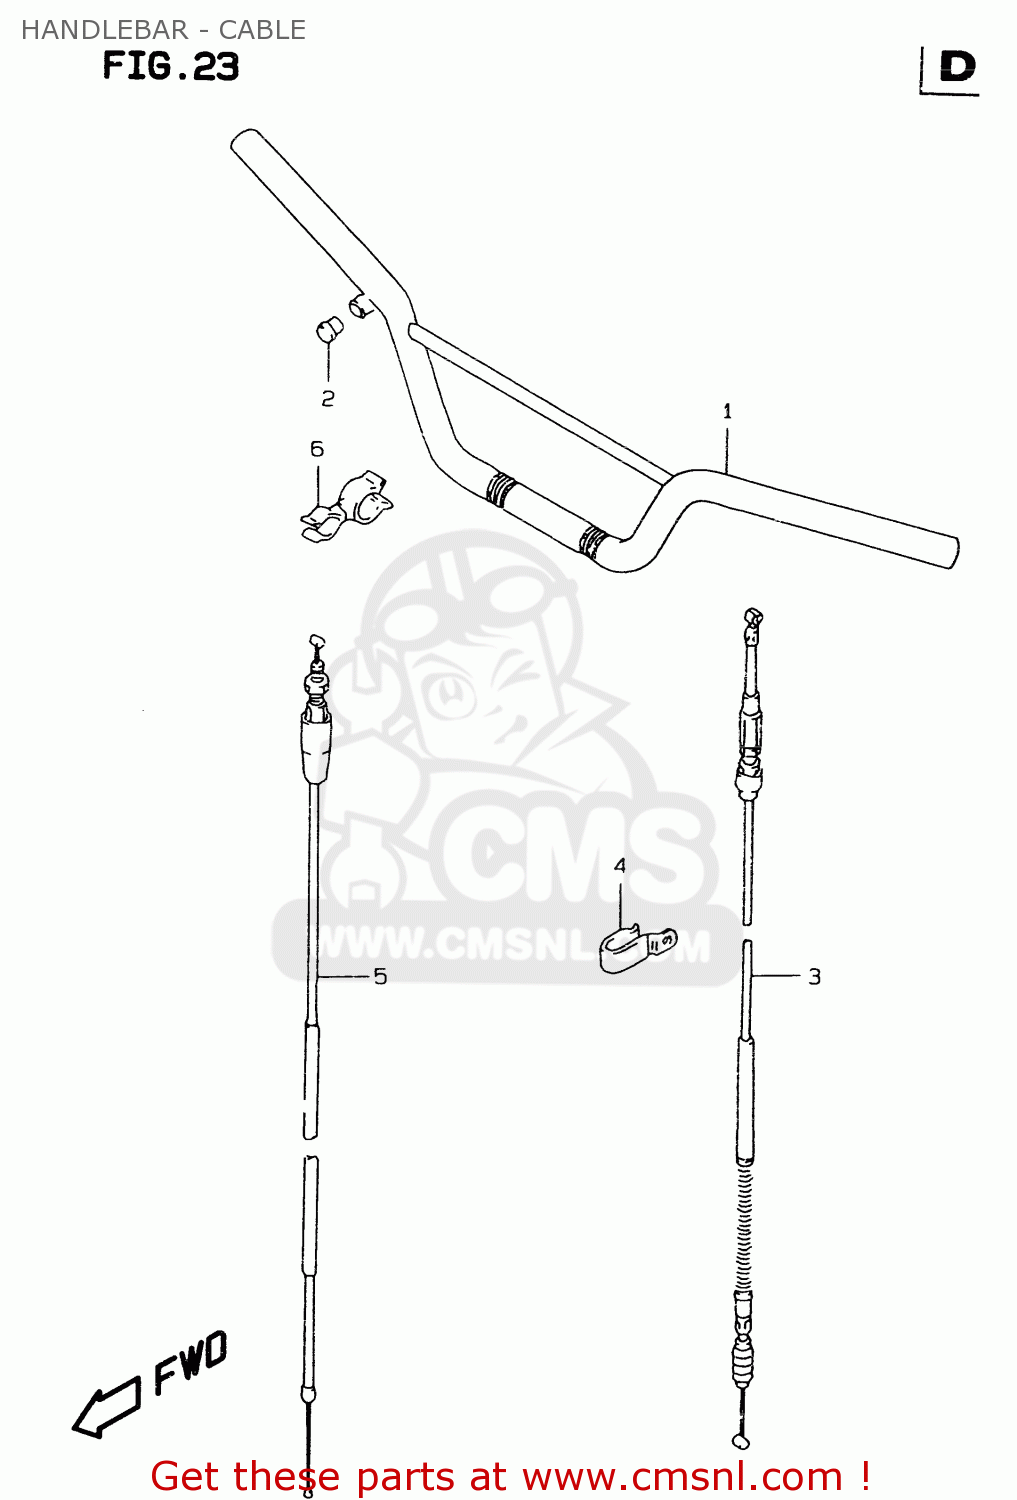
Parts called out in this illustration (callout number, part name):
1	HANDLEBAR COMP
2	CAP(OD:14)
3	CABLE ASSY,CLUTCH
4	CLAMP
5	CABLE ASSY,THROTTLE
6	CLAMP
